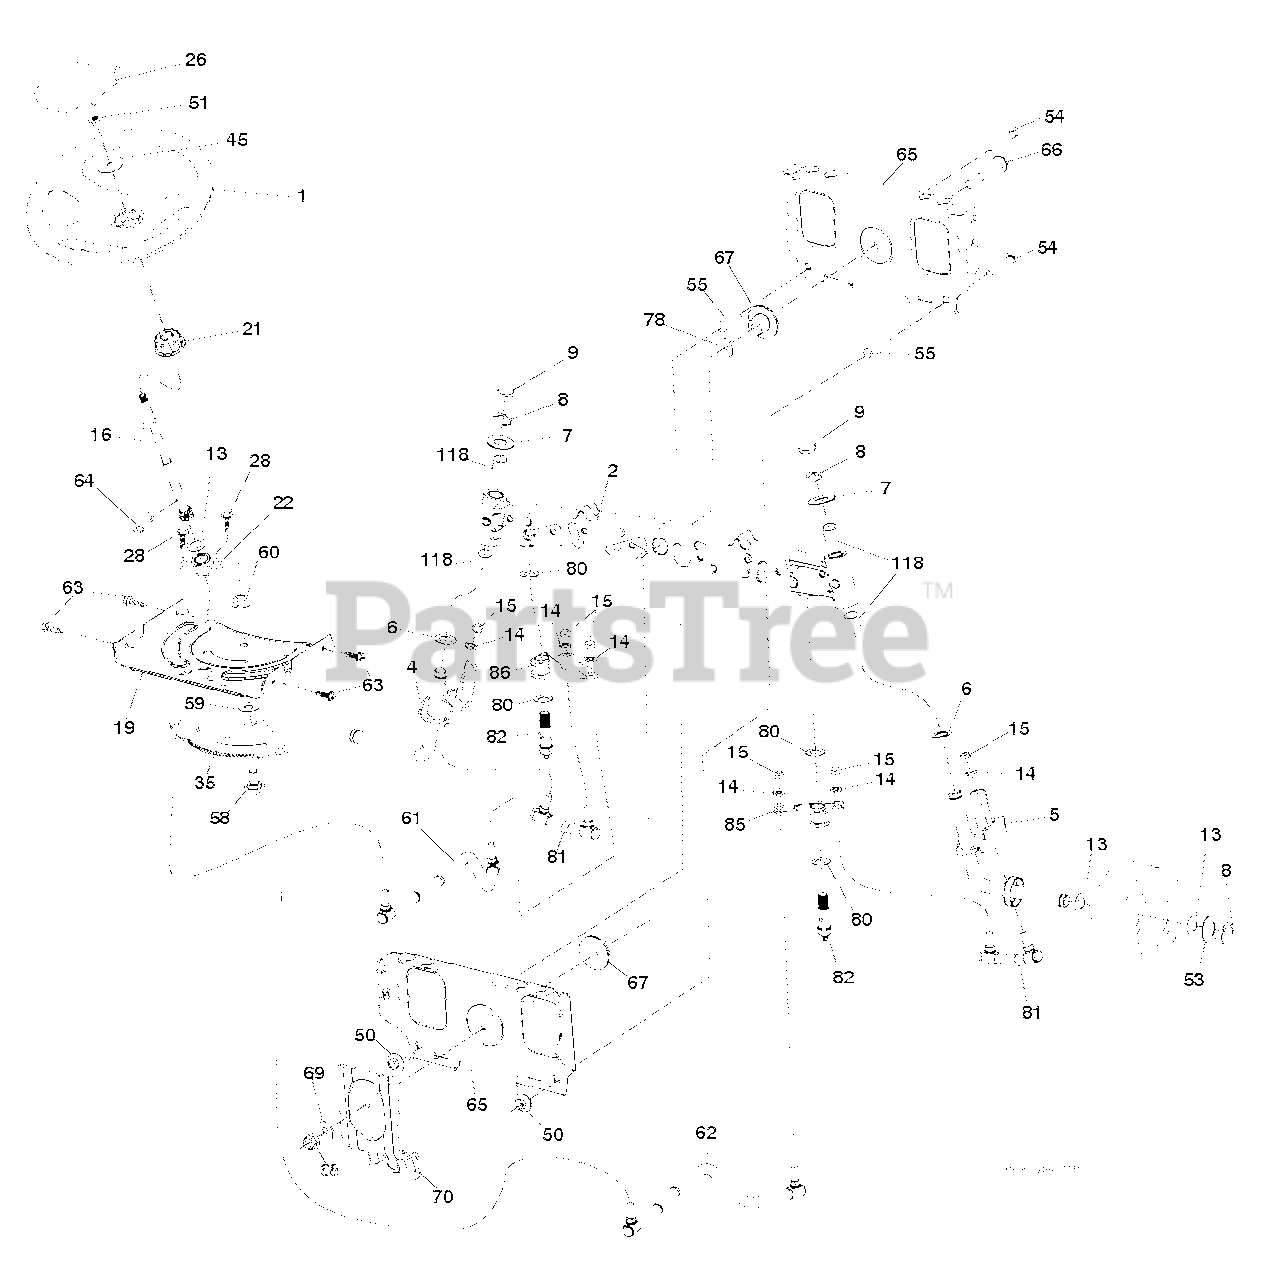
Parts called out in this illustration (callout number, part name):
1	WHEEL.STEER.HUSQ.SR.498.OVMLD
2	RP SUBASM.AXLE.CAST.NZTR.
4	SPINDLE WELDMENT.SPINDLE.LH.15
5	SPINDLE WELDMENT.SPINDLE.RH.15
6	THRUST WASHER
9	CAP.SPINDLE.BLACK
14	WASHER, LOCK 3/8
15	NUT CROWNLOCK 3/8-24
16	SHAFT SHAFT.STEERING.2HIGH.PLA
19	PLATE.STEER.DDL.NLT/NG
21	RP STEERING.WHEEL.ADAPTER
22	BUSHING.ASM.STEERING.A
26	INSERT.CAP.WHL.STRG.HUSQ.PREM
28	SCREW, 3/8-16X3/4
35	GEAR GEAR.SECTOR.TEX.NZTR
45	WASHER 9/16"ID, 2 3/8"OD
50	NUT LOCK FLG 3/8-16 UNC
51	NUT.HEX.1/2-20
53	WASHER.HARDENED
55	SPACER.BRACE.AXLE
58	BOLT.SHOULDER.SECTOR.P
59	WASHER.THURST.SECTOR.S
60	NUT FLANGE LOCK 5/8-11
61	LINK SUBASM.LINK.DRAG.LH.NZTR
62	TUBE TUBE
63	SCREW
64	RETAINER.CLIP.SPRING.S
65	BRACE.AXLE.FRONT.NLT/N
66	BOLT HEX FGHD 7/16-14 X 3 SERR
67	BUSHING.PM.FRONT AXLE
68	NUT.LOCK.FLANGE.7/16
69	WASHER.1.5X.505X.118
70	BRKT.DECK.SUSPENSION.F
78	THRUST WASHER
80	THRUST WASHER
81	LINK SUBASM.LINK.CROSS.NZTR
85	PIVOT SUBASM.PIVOT.RH.NZTR
118	BUSHING, AXLE CAST
